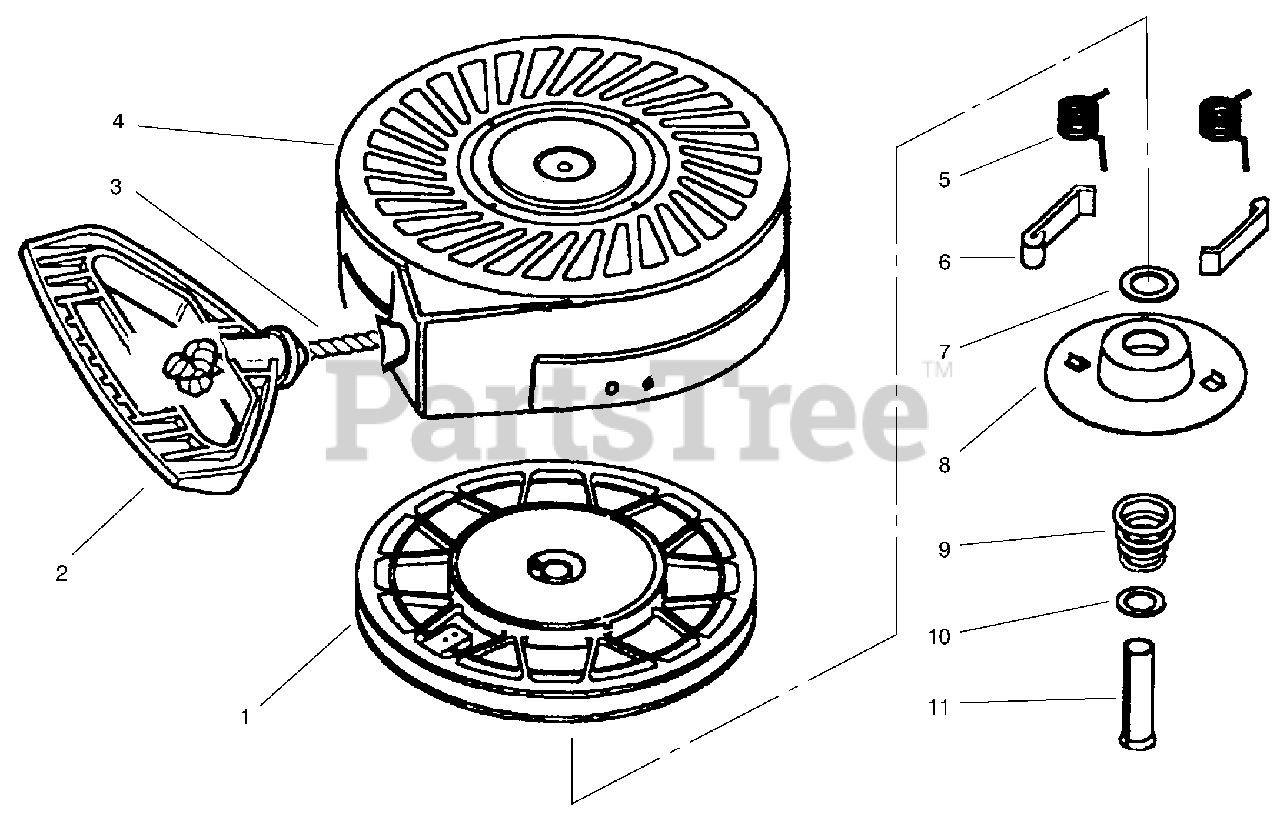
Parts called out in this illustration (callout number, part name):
2	Handle-Starter
3	Rope Starter
4	Housing Assembly
5	Dog Spring
6	Dog-Starter
8	Retainer
9	Brake Spring
11	Pin-Spring (Incl. Ref. # 7)
